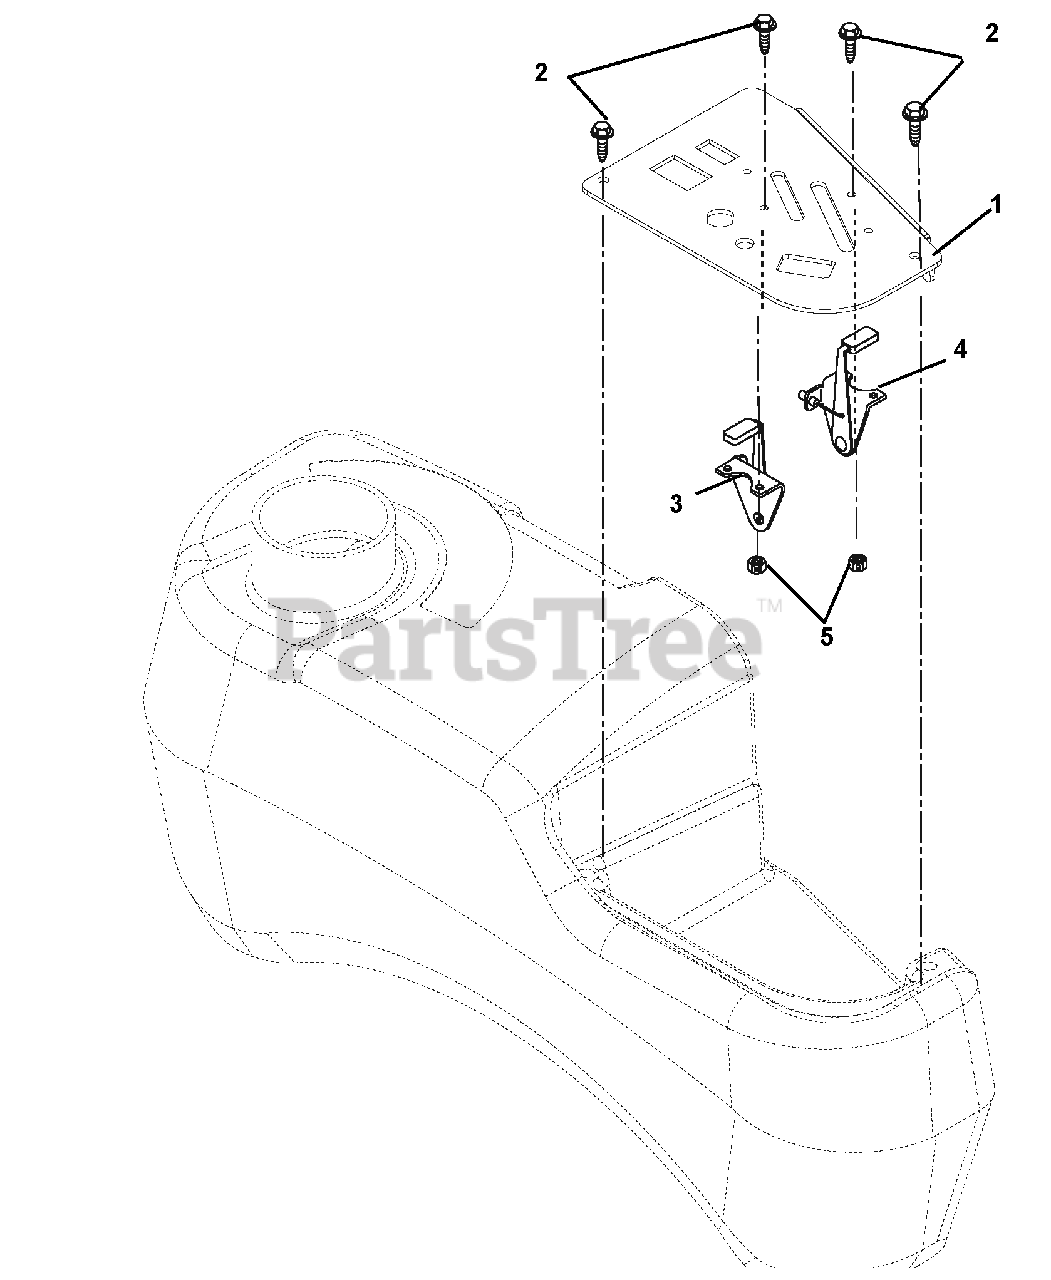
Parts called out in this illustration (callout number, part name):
1	PANEL, CONTROL IZ - BLACK
2	@SCR-MCH 10-24X.50 HWH YWZC
3	CABLE, THROTTLE, IZ (KAW)
4	CABLE, CHOKE KAW IZ
5	@NUT-LK-NYL 10-24 W/INSRT YWZC
